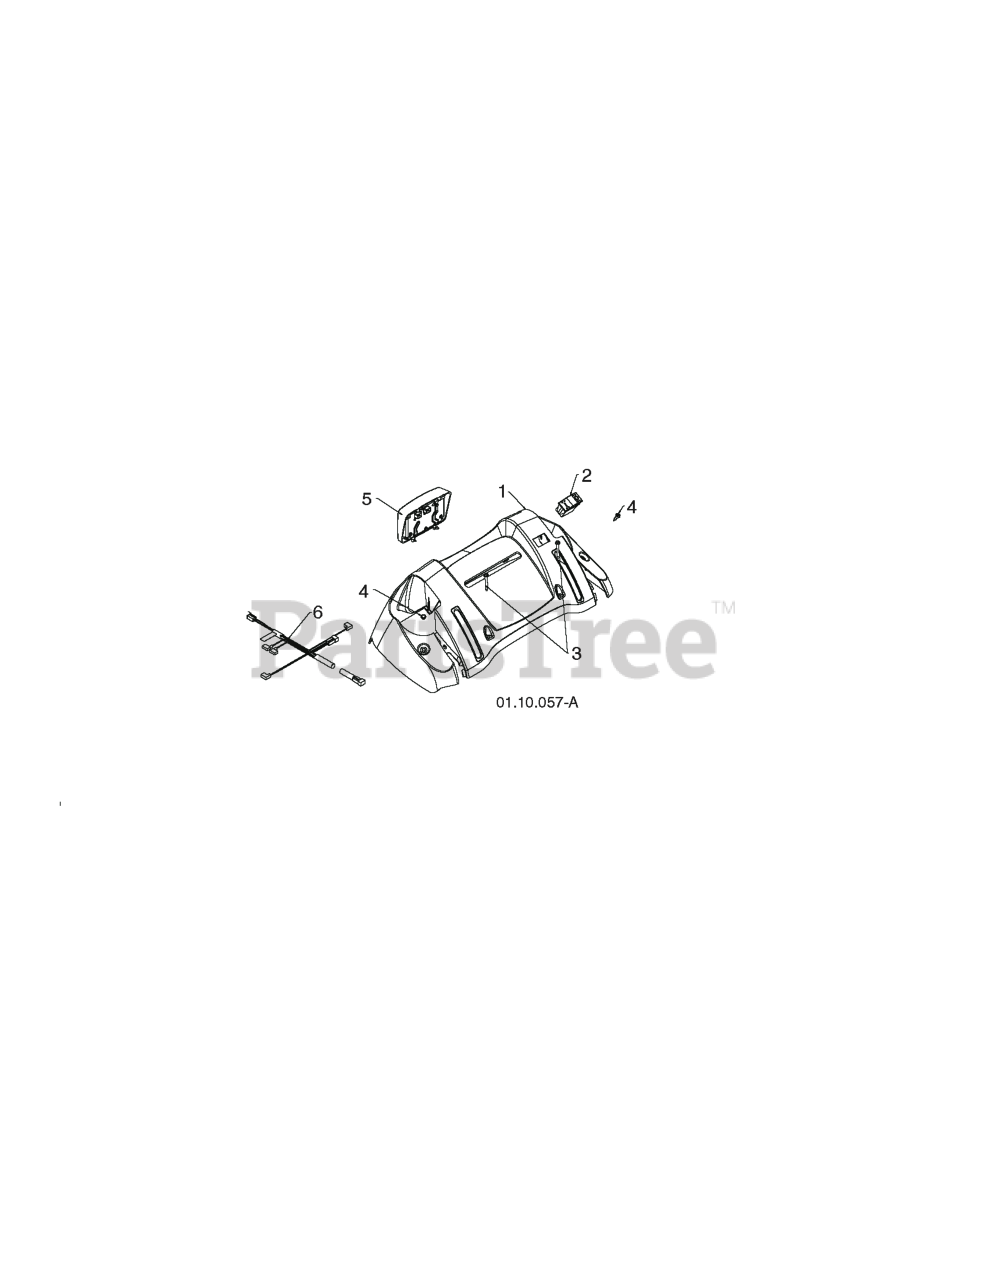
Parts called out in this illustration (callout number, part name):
1	PANEL.CONSOLE.
2	SWITCH.HEATED.GRIP
3	SCREW, HEX HD TAPPING #10-24 1
4	SCREW, HEX HEAD, TAPPING
5	HEADLIGHT.LED.DUAL STAGE.GREY
6	HARNESS.WIRE.FLOOD/LED.HEAT.
